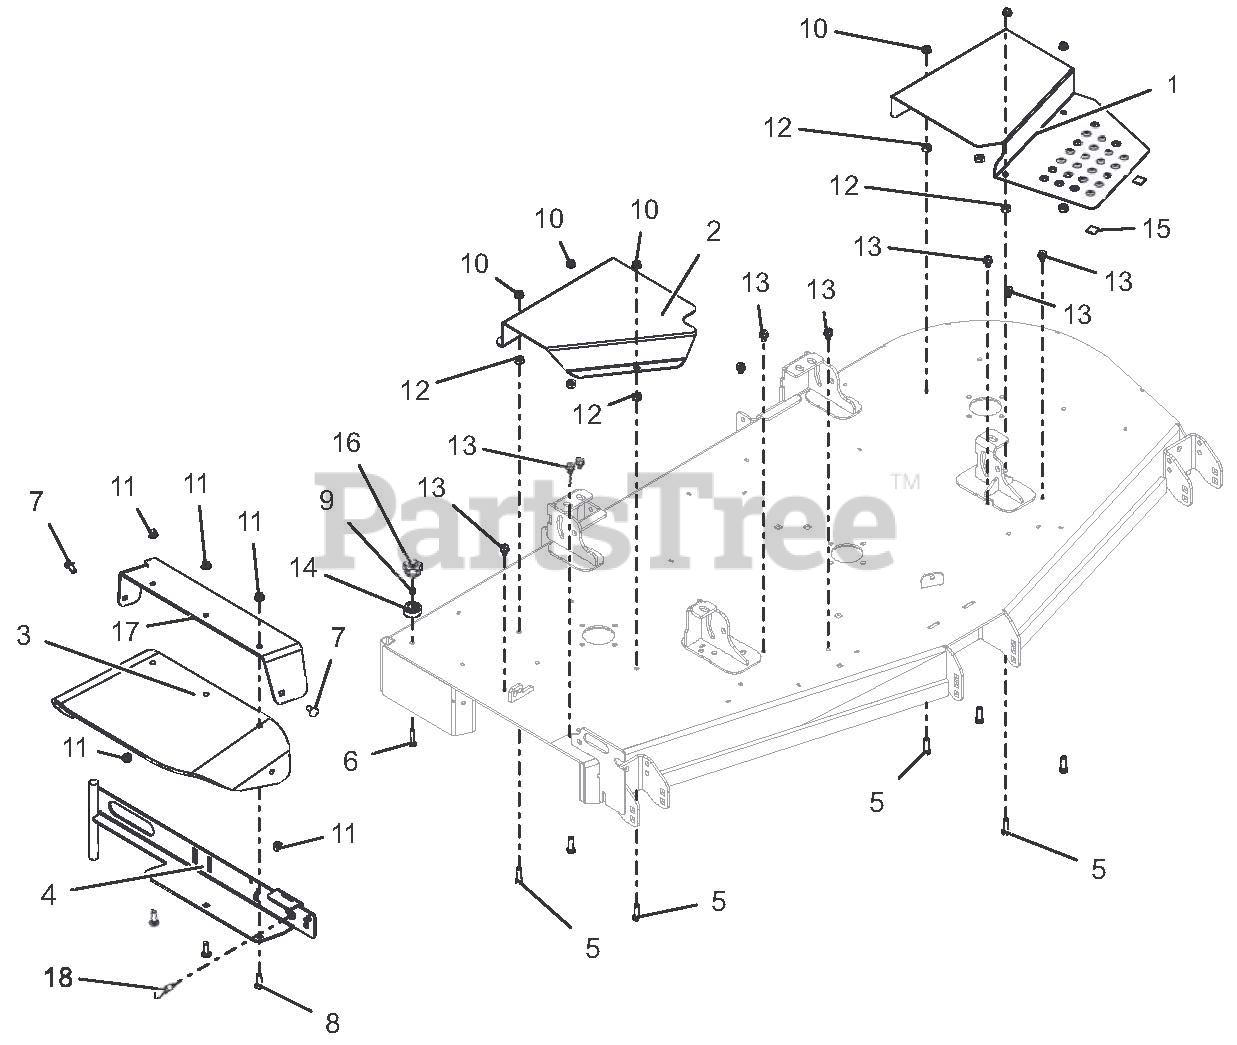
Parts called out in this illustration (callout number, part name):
1	GUARD, 72" LH DECK BELT
2	GUARD, 72" RH DECK BELT
3	CHUTE, RUBBER DISCHARGE
4	WLDMT, 72" DISCH CHUTE MTG
5	BLT-HEX .38-16 X 1.25 GR5 YWZC
6	BLT-RDHDSQNK .31-18 X 1.50 G5 YWZC
7	BLT-RDHDSQNK .38-16 X 1.00 G5 YWZC
8	BLT-RDHDSQNK .38-16 X 1.25 G5 YWZC
9	NUT-LK-CTR .31-18 YWZC
10	@NUT-SPNLK-FLG .375-16 YWZC
11	NUT-LK-NYL-FLG .38-16 YWZC
12	NUT-HEAVY HEX .38-16 YWZC
13	SCR-TAP .38-16 X .50 HWH TR YWZ
14	BUMPER, RECESSED 1.50 X .63 W/.31 HOLE
16	KNOB, CLAMPING
17	DISCHARGE CHUTE SUPPORT W/SAFETY DECAL
18	PULL PIN,.50-13THDX.310 PLNGR
